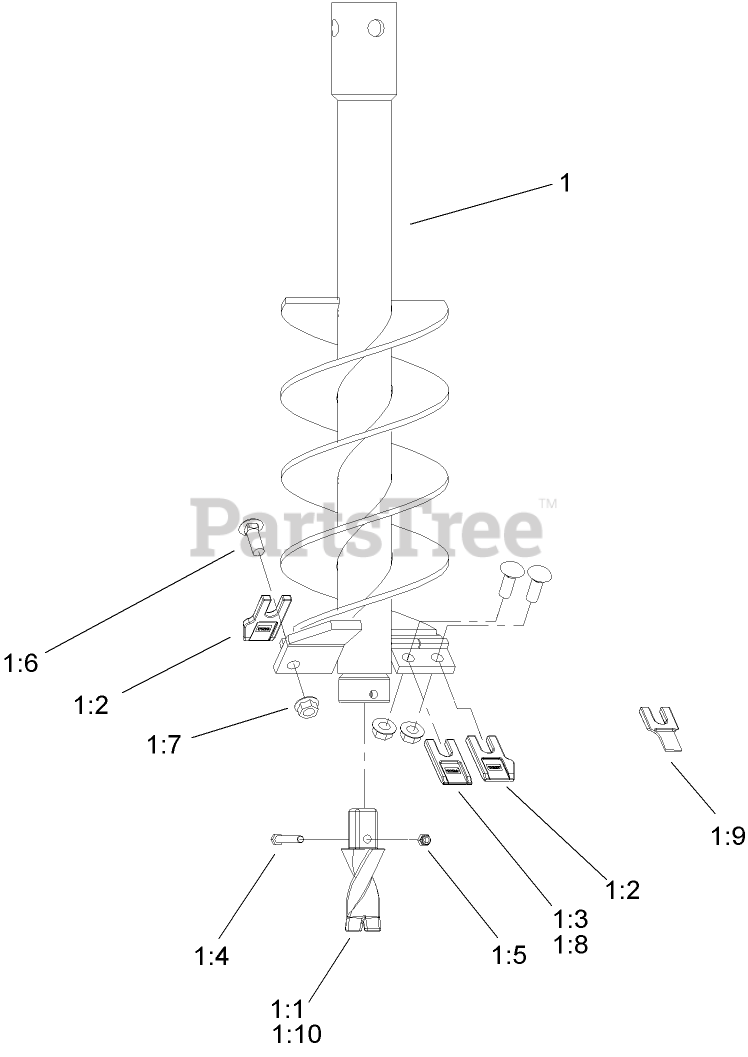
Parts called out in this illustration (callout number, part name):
1	AUGER-9 Inch
1:1	FISHTAIL-SHANK, SQUARE
1:2	TOOTH-AUGER, GAGE
1:3	TOOTH-AUGER, WISDOM
1:4	SCREW-HH
1:5	NUT-LOCK, NI
1:6	SCREW-CARR
1:7	NUT-LOCK, NI
1:8	TOOTH-WISDOM, CARBIDE
1:9	TOOTH-CHISEL, CARBIDE
1:10	PILOT-HARDFACED
